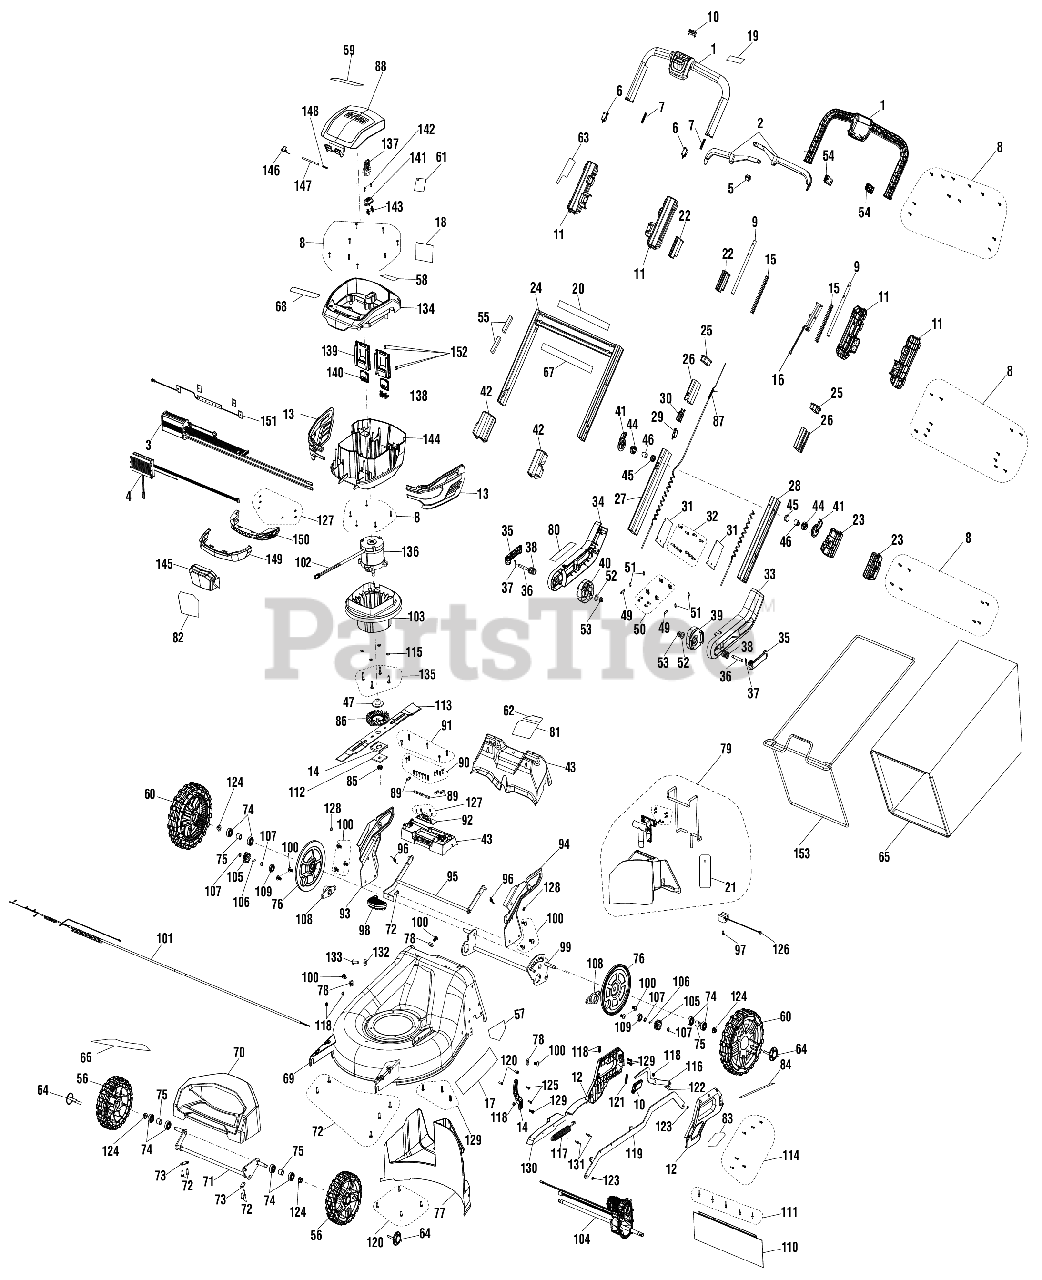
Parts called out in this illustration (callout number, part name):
1	Upper Handle Assembly
2	Trigger Assembly
3	Drive Motor Controller
4	Blade Circuit Board Controller
5	Stop Switch (Momentary Contact)
6	Switch (Red)
8	Screw (M4 x 18 mm, T20 Torx Pan Hd.)
9	Guide Tube
10	Blade Button Trigger Assembly
11	Upper Handle Housing
12	Deck Height Adjustment Housing
13	Battery Housing Vent Assembly
14	Transmission Mount & Spacer Assembly
15	Compression Spring
16	Speed Sensor Switch Assembly
17	Deck Size Label
18	Main Danger Label (SP)
19	Starting Instructions Label
20	Handles Fully Extended Label
21	Mulch Plug Hangtag
22	Slide Bushing Assembly
23	Rear Handle Latch Assembly
24	Structural Frame Assembly
25	Telescoping Latch
26	Telescopic Bushing
27	Tube (Right)
28	Tube (Left)
30	Fix Bushing Switch
31	Handle Cover
32	Screw (M5 x 14 mm)
33	Lower Handle (Left)
34	Lower Handle
35	Handle Cam Lever
37	Cam Lever Dowel (4 mm)
38	Compression Spring
39	Handle Height Adjustment Disc (Right)
40	Handle Height Adjustment Disc (Left)
41	Side Handle Latch
42	Front Handle Latch Assembly
43	Bag Hanger
44	Side Compression Disc Holder
45	Handle Compression Spring
46	Rubber Compression Disc
47	Motor Shaft Bushing
48	Handle Latch (Right Front)
49	Wiring Strap (20 mm)
50	Screw (M4 x 12 mm, T20 Torx Hd.)
51	Wiring Hold Down Plate (10 mm)
52	Washer (OD24 x ID12.5 x 2.5t)
53	Flange Nut (M8, Flywheel)
54	Push Button
56	8 in. Wheel Assembly
57	Danger Label (No Hands/Feet)
58	Onboard Battery Storage Label
59	Main Danger Label (EN/FR)
60	10 in. Wheel Assembly
61	Start Key Hangtag
62	Attachment User Callout Label
63	Handle Lockout Label
64	Wheel Hub
65	21 in. Grass Bag
66	Front Logo Label
67	Handle Logo Label
68	Start Key Warning/Data Combo Label
69	21 in. Deck Assembly
70	Front Bumper Cover Assembly
71	Front Axle.
72	Screw (1/4-15 x 3/4 in., T30 Torx Pan Hd.)
73	Front Axle Mount
74	Ball Bearing (ID12 x OD32 x 10 mm)
75	Wheel Bushing
76	Wheel Cover
78	Square Nut (M8)
79	Mulching Plug Assembly
80	Handle Instructions Label
81	Guard Warnings Label
82	Logo Label (Front)
83	Single Point Adjust Label
84	Cut Height Label
85	Blade Nut (M10 x 1.25, Hex Flange Hd.)
86	Motor Fan Blade Adapter
87	Inner Wire w/Terminal
88	Battery Cover Assembly
89	Wire Press Plate
90	Screw (M4 x 16 mm, T20 Torx Pan Hd.).
91	Screw w/Washer (M4 x 16 mm, T25 Torx Truss Hd.)
92	Signal Conversion Interface Board
93	Handle Bracket (Right)
94	Handle Bracket (Left)
95	Pedal Linkage
96	Extension Spring
97	Screw w/Washer (M4 x 10 mm, T20 Torx Button Hd.)
98	Handle Latch Pedal
99	Rear Axle w/Height Adjustment Plate
100	Screw (M8 x 16 mm, T40 Hex Hd.)
101	Main Wiring Harness (Right)
102	Main Wiring Harness
103	Motor Mount
104	Transmission
105	Drive Gear
106	Gear Shaft
107	Retaining Ring
108	Drive Axle Bearing Sleeve
109	Ball Bearing (OD28.6 x ID12.7 x 8)
110	Rear Guard
111	STEEL RIVET DIA 3.9 X 8MM
112	Metal Blade Retainer
113	21 in. Blade
114	ST SCREW,STEEL CH M4.0X1.8 PH TORX
115	Washer (ID6.2 x OD15 x 0.08t)
116	Height Adjustment Hook
117	Extension Spring
118	Lock Nut (M6 x 6 mm)
119	Height Adjustment Linkage
120	Screw (M6 x 14 mm, Hex Soc. Hd.)
121	Height Adjustment Trigger Spring
122	Clutch Shoulder Bolt (M6 x 22.5 mm, Hex Hd.)
123	E-Ring (ID 6 mm)
124	Lock Nut (3/8-16, Flange)
125	Screw (T20 x 12 mm)
126	Grass Catcher Sensor Switch
127	Screw (M3 x 8 mm, Pan Hd., Pan Hd)
129	Screw (M6 x 20 mm, T27 Torx Button Hd.)
130	Spring Cover
132	Washer (ID 4.3 x OD12 x 1.5t)
134	Top Battery Housing Cover
135	Bolt (M6 x 26 mm, Hex Hd.)
136	40V-DC Motor
137	Key Assembly
138	Common Foot Contact Plate
140	Common Foot Cover
141	Key Holder
142	Screw (M4.2 x 12 mm, T20 Torx Pan Hd.)
143	Female Terminal
144	Battery Housing (Bottom)
145	Plug Cover Battery Housing (Front)
146	Battery Clear Cover Spring
148	Compression Spring
149	LED Clear Window Lens
150	LED Reflection Cup
151	LED Circuit Board Assembly
152	Screw (M3 x 10 mm, T10 Torx Hd.)
153	Bag Frame
